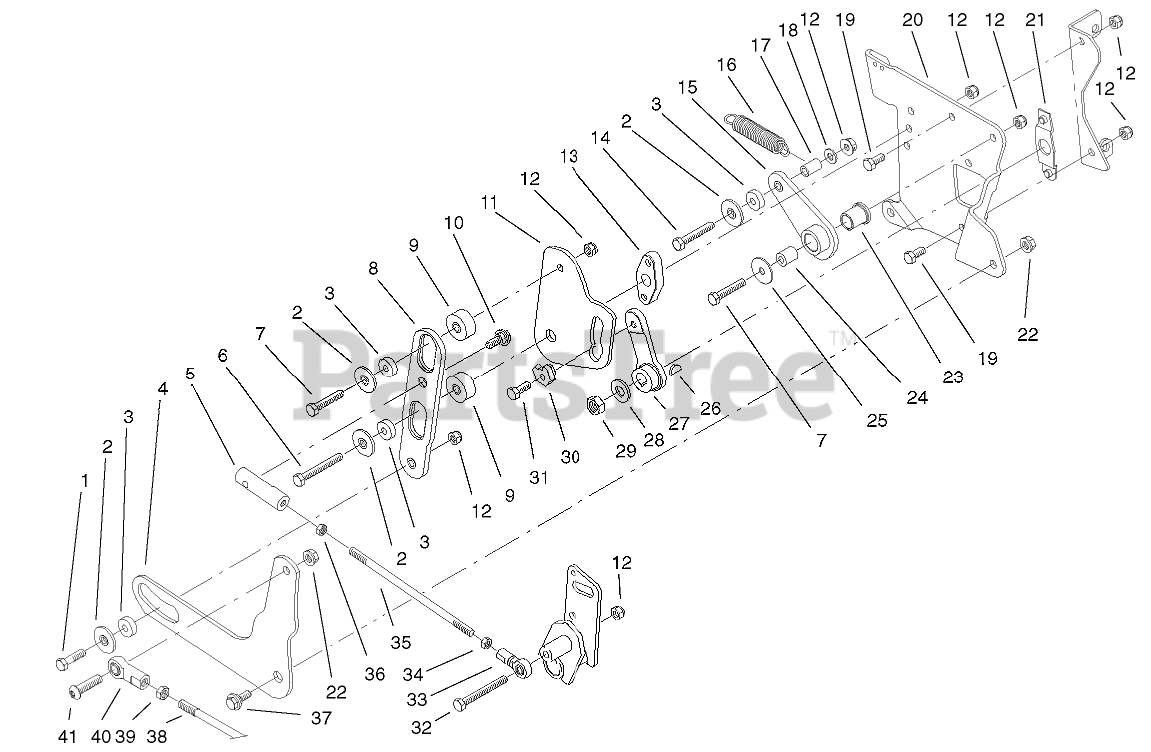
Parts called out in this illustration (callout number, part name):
1	SCREW-HH
2	RETAINER-BEARING
3	BEARING-BALL
4	SLIDER-LIFT
5	END-ROD, RH
6	SCREW-HH
7	SCREW-HH
8	SLIDER-CONTROL, SPEED
9	STANDOFF-CAM PLATE
10	BOLT-SHOULDER
11	PLATE-CAM
12	NUT-LOCK, NI
13	STANDOFF-SLIDER
14	SCREW-HH
15	ARM-RETURN TO NEUTRAL
16	SPRING-IDLER
17	STANDOFF-SPRING
18	WASHER-PLAIN
19	SCREW-HH
20	PLATE-CONTROL
21	LOCATOR-CONTROL PLATE
23	BUSHING-FLANGED
24	SPACER
25	WASHER-FLAT
26	KEY-WOODRUFF
27	ARM-CONTROL, SPEED
28	WASHER-FLAT
29	NUT-LOCK, NI
31	SCREW-THREAD LOCKING
32	SCREW-HH
33	END-ROD, RH
34	NUT-JAM
35	ROD-SLIDER TO PIVOT
36	NUT-JAM
37	BOLT-SHOULDER
38	ROD-LIFT
39	NUT-HJ
40	END-ROD, FEMALE
41	SCREW-HSBH
